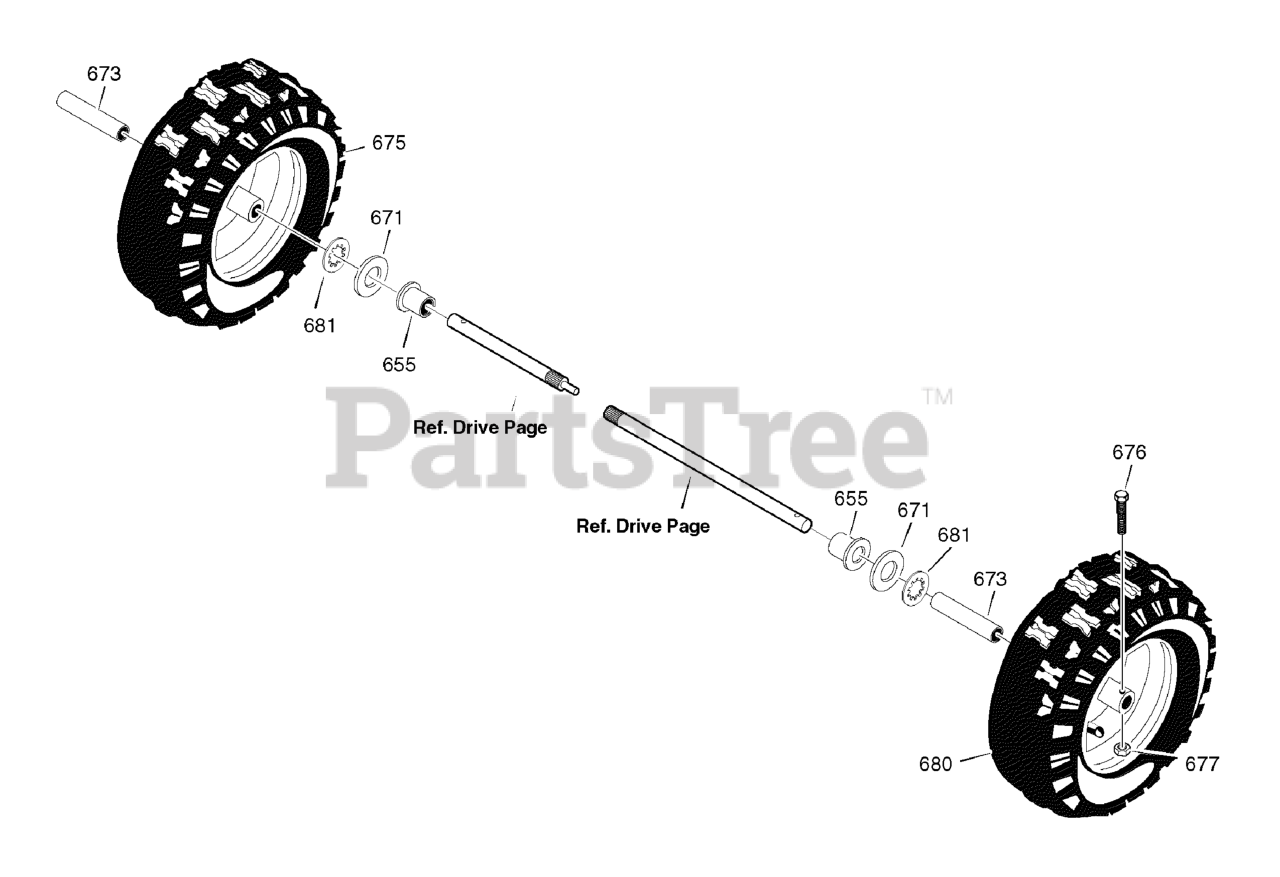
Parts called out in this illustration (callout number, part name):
655	BEARING, Axle
671	WASHER, Flat
673	BUSHING, Wheel
675	TIRE & RIM, Right
676	SCREW, 1/4-20 X 1.75 HH
677	NUT, Hex, Nylock, 1/4-20
680	TIRE & RIM, Left
681	RING, Retaining, Self-Locking
